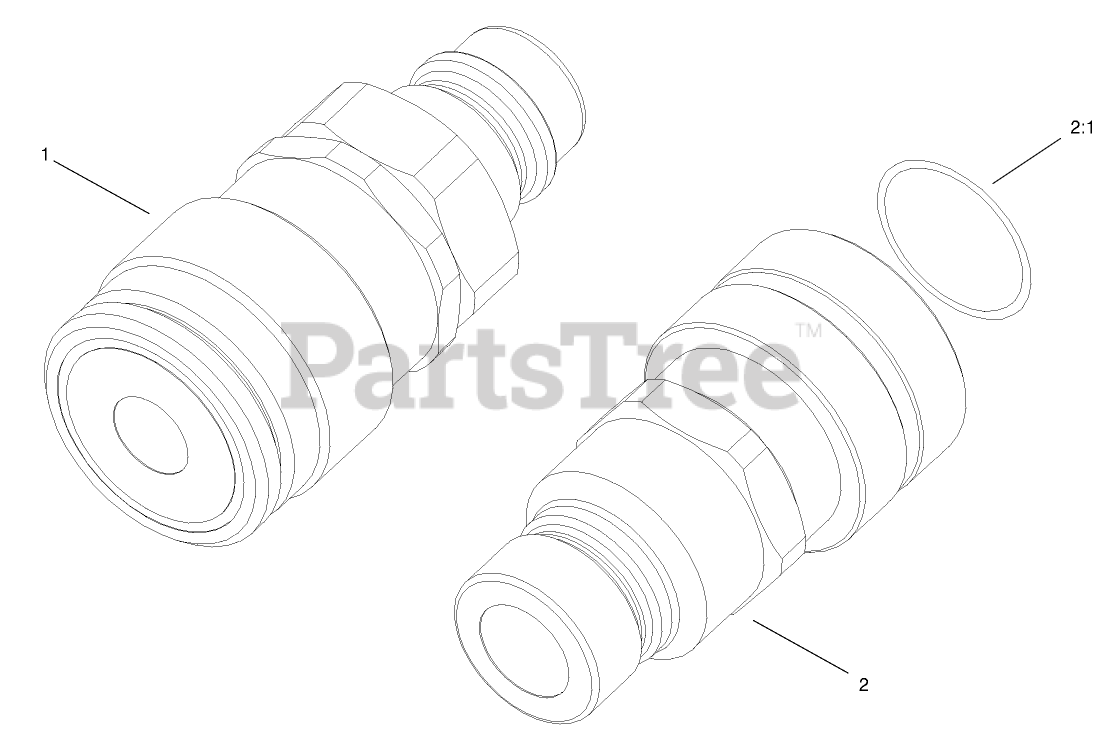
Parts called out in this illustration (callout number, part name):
1	ADAPTER-CONVERTER, EAS
2	ADAPTER-CONVERTER,SAE
2:1	KIT-SEAL,
